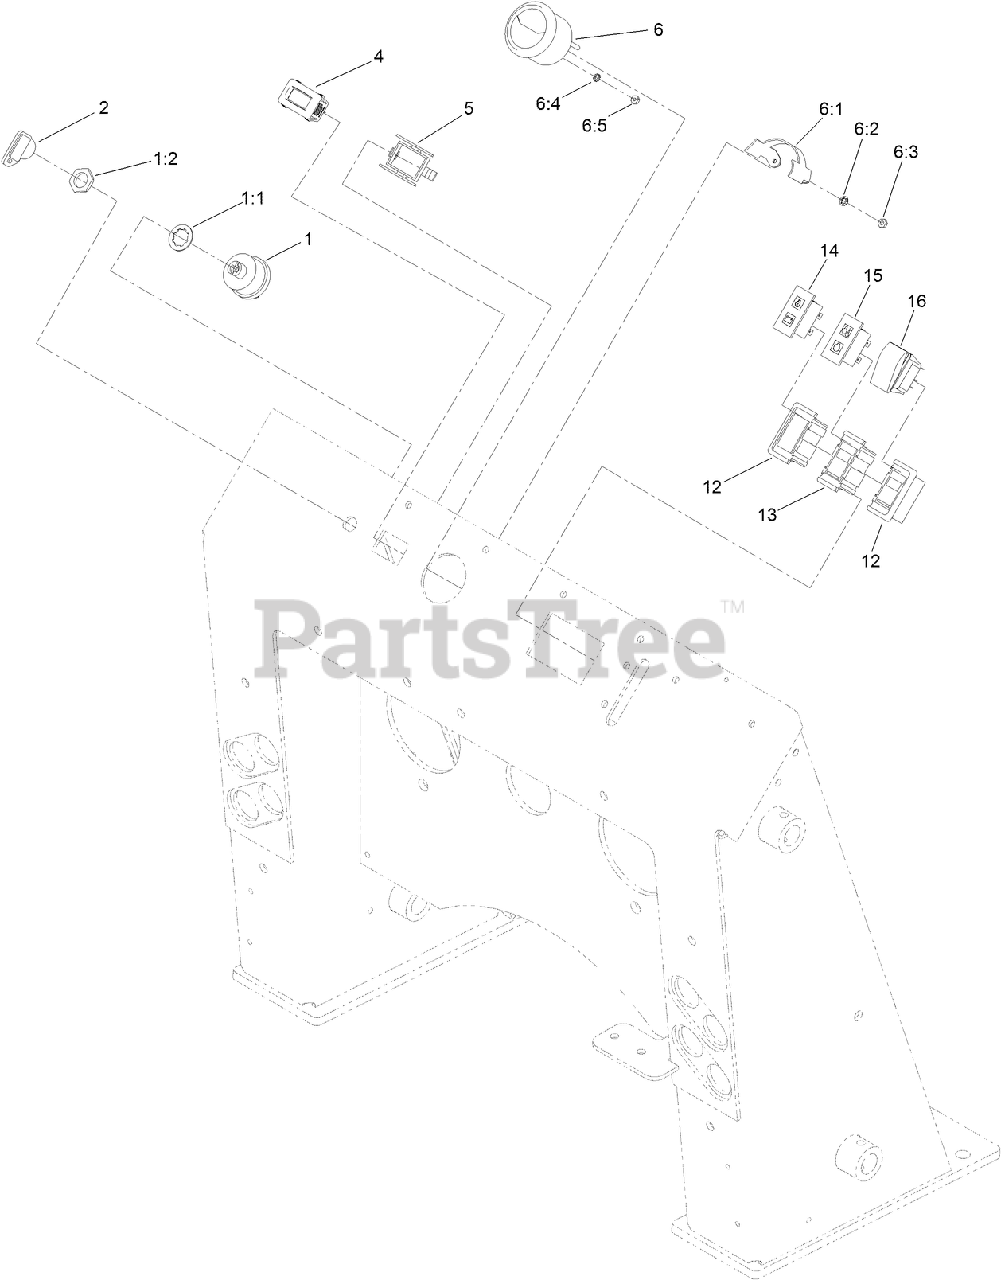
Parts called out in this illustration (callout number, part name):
1:1	WASHER-LOCK
1:2	NUT-HH
2	KEY-IGNITION
4	HOURMETER
5	CLIP-MOUNTING
6	GAUGE-FUEL
6:1	BRACKET-MOUNTING, GAUGE
6:2	WASHER-LOCK, INT
6:3	NUT-HEX
6:4	WASHER-LOCK / EXT
6:5	NUT-HEX
12	BRACKET-END
13	BRACKET-MIDDLE
14	LAMP-WARNING
15	LAMP-WARNING
16	SWITCH-ROCKER
